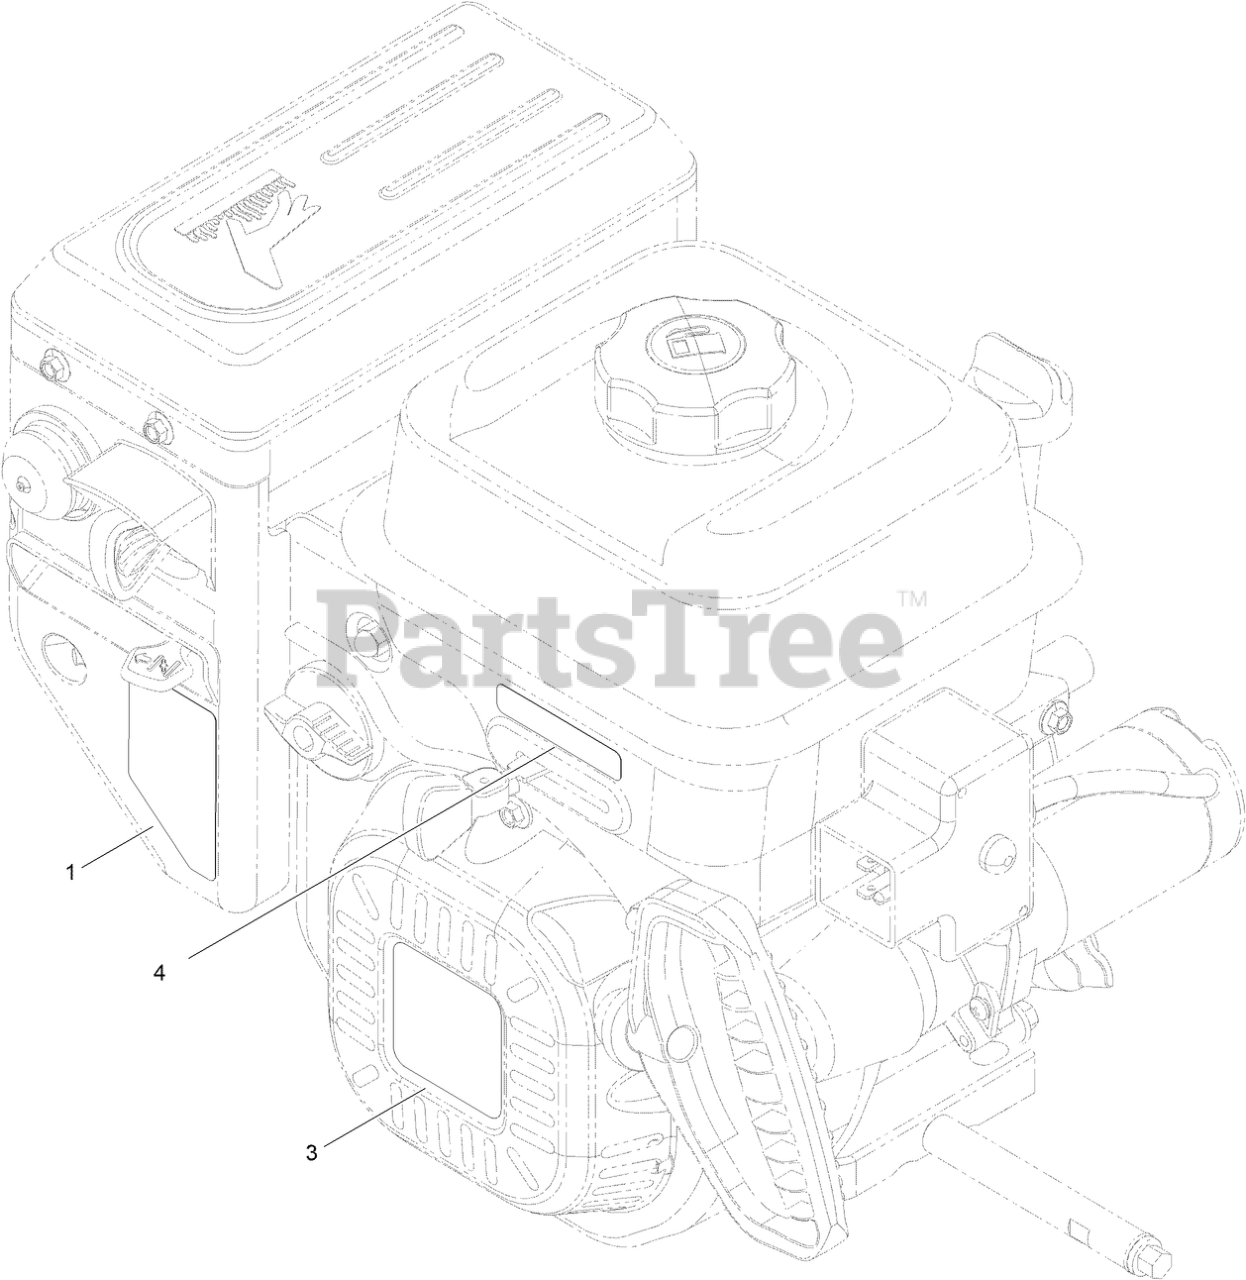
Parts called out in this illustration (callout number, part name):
1	DECAL-CONTROL, ENGINE
3	DECAL-RECOIL, G210
4	DECAL-THROTTLE
